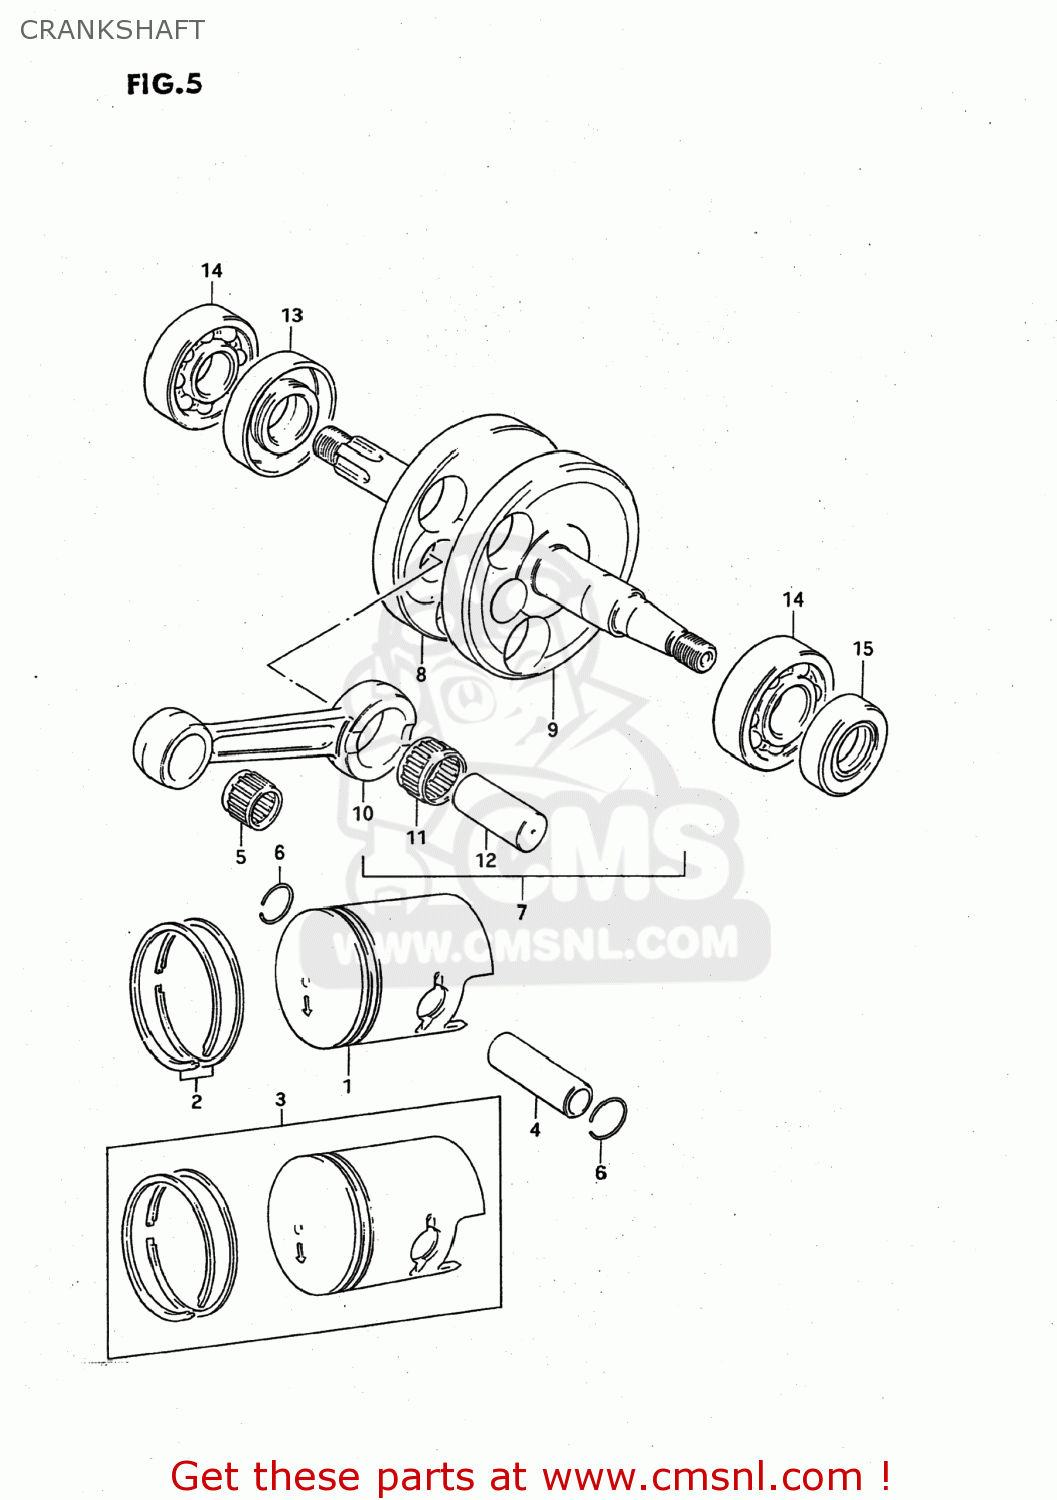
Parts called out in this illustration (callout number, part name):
1	PISTON (41.00MM)
2	RING SET,PISTON
3	PISTON SET (OS:0.5)
4	PIN,PISTON
5	ROLLER BEARING (12X16X1
6	RING,SNAP
7	CRANKSHAFT ASSY
8	CRANKSHAFT,R
9	CRANKSHAFT,L
10	ROD,CONNECTING
11	BEARING(15X21X9.8)
12	PIN,CRANK
13	SEAL,OIL(22X40X8)
14	BEARING(17X40X12)
15	OIL SEAL (17X29X7)
